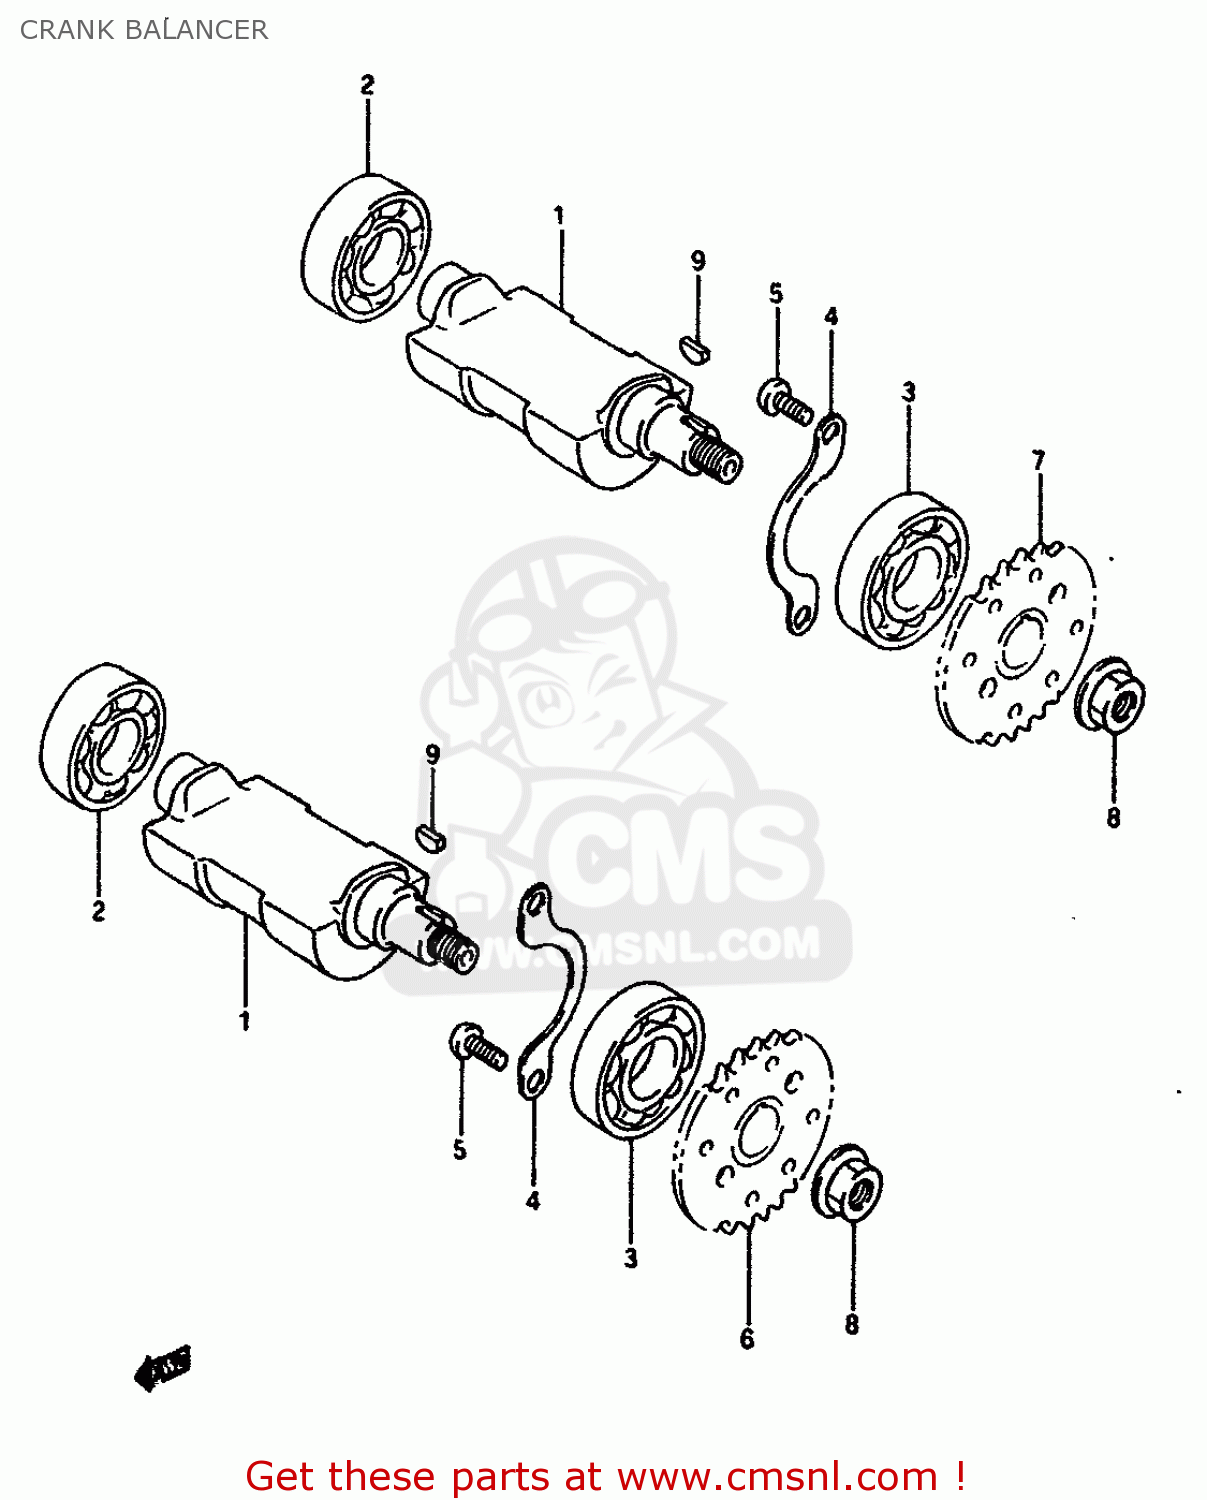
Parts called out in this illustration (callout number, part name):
1	BALANCER,CRANKSHAFT
2	BEARING(20X42X12)
3	BEARING(20X47X12)
4	RETAINER,CRANK BAL BEARING
5	SCREW
6	SPROCKET,BALANCER DRIVE
7	SPROCKET,BALANCER DRIVEN RR
8	NUT
9	KEY
